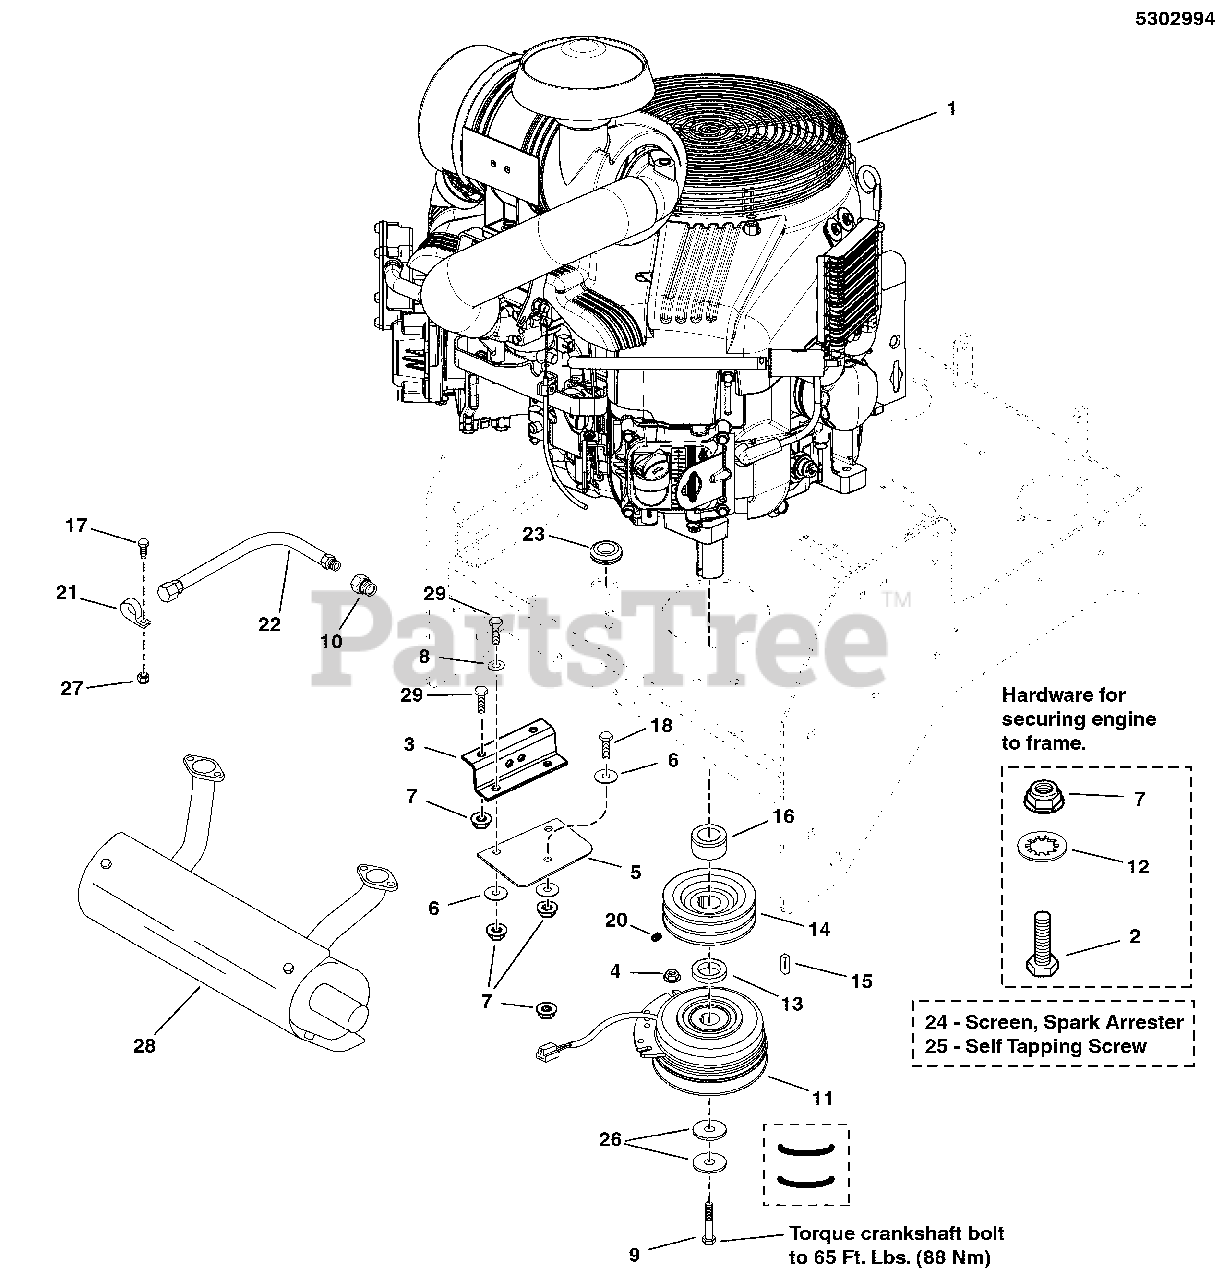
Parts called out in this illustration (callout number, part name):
1	* ENGINE, BRIGGS & STRATTON
2	BOLT, 5/16-18 X 1-3/4" GD5 YZ
3	ANCHOR, CLUTCH - BLK
4	NUT, 5/16-18 HEX SERRATED FLANGE (LARGE)
5	CLUTCH ANCHOR PAD
6	WASHER, 3/8" Fender
7	NUT, 5/16-18 HEX NYLOCK FLANGE NUT
8	WASHER, 5/16" SAE
9	BOLT, CRANKSHAFT, 7/16 X 2-3/4, PATCH, CZ
10	METRIC ADAPTER, M14-1.5" TO 3/8 NPTF
11	CLUTCH WARNER 200 FT-LB 1.13 X 6.323
12	WASHER, 5/16" Internal Tooth Lock
13	SPACER, 1.13 X 1.75 X .50
14	PULLEY, CRANKSHAFT, 1.126 ID X 4.75 OD
15	KEY, 1/4 SQ X 1
16	SPACER, 1.13 X 1.75 X 1.09, PM
17	BOLT, 1/4-20 X 1" GD5 CZ
18	BOLT, 5/16-18 X 2-1/4 TFL, GD5 YZ
20	SET SCREW, 5/16-18 X 3/8, KNURL, W/PATCH
21	CLAMP, VINYL INSULATED, 1.00
22	HOSE, OIL DRAIN
23	GROMMET, 7/8"
24	* SCREEN, SPARK ARRESTER
25	SCREW, SELF-TAP, #8-32 X 3/8. WASH HEX, CZ
26	BELLEVILLE WASHER, 1.1875 X .442 X .098
27	NUT, 1/4-20 Hex Nylock Flange
28	MUFFLER
29	BOLT, 5/16-18 X 1" GRD5 YZ
